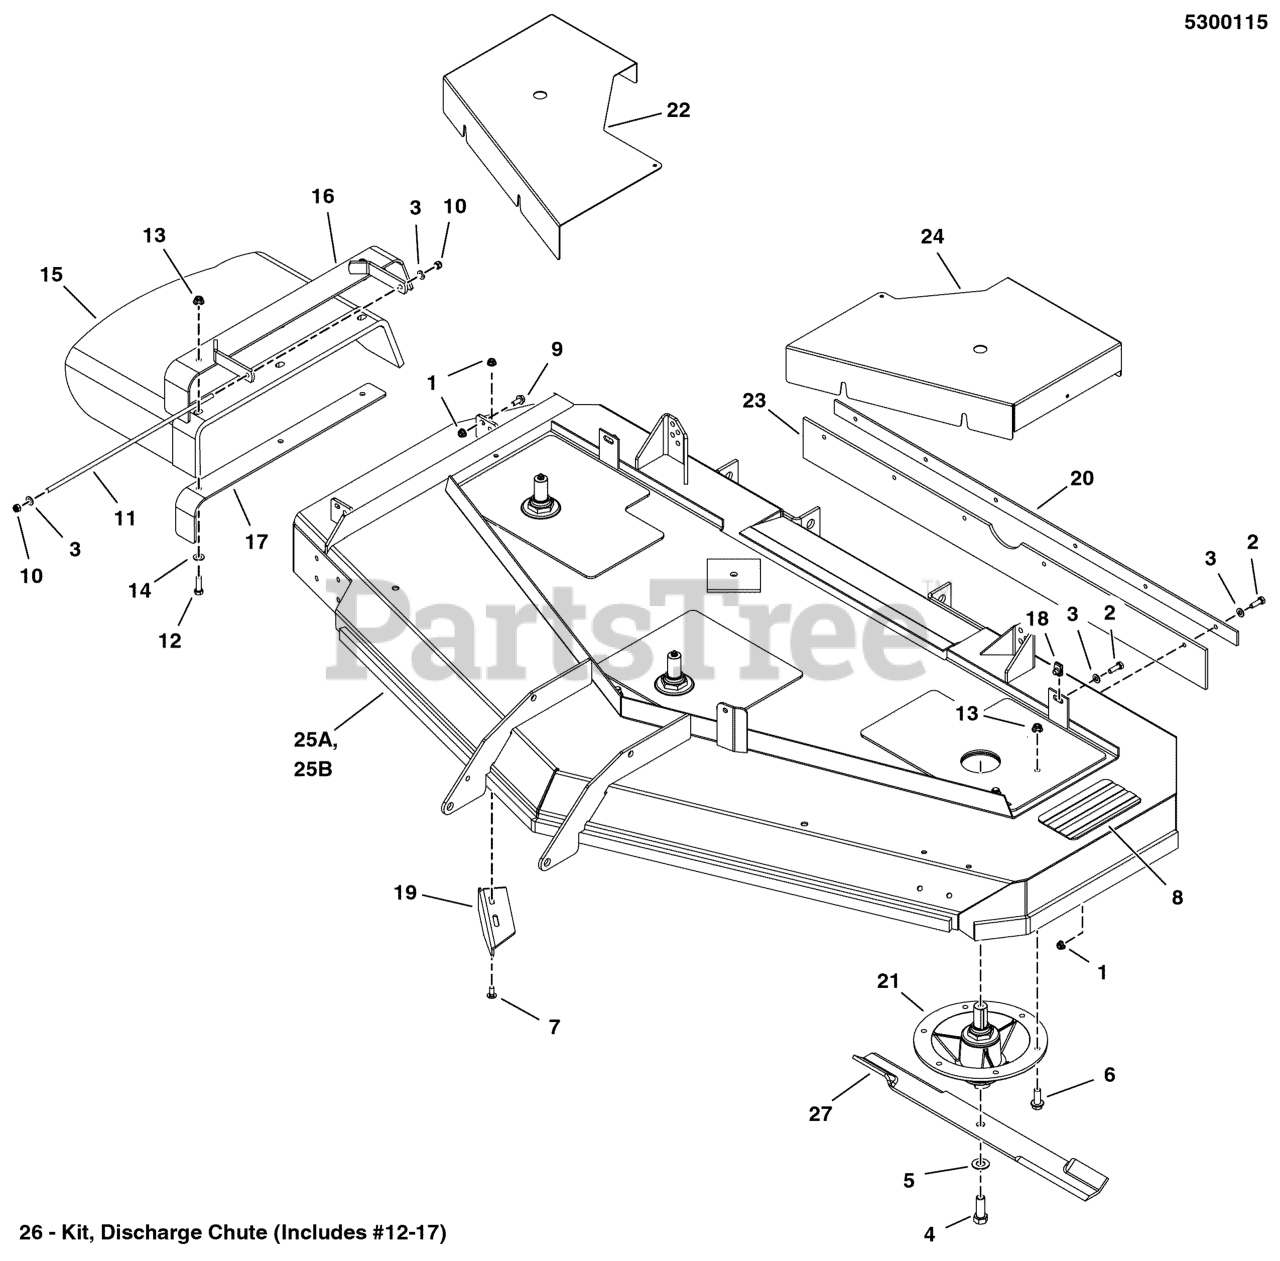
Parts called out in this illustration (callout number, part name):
1	NUT, 5/16-18 HEX NYLOCK FLANGE
2	BOLT, 5/16-18 X 1 GD5 YZ
3	WASHER, 5/16" SAE
4	BOLT, 5/8-11 X 1-3/4 GD8
5	WASHER, 5/8 GRADE 8, YZ
6	BOLT, 3/8-16 X 1-1/4, FLANGE, GD 5, CZ
7	BOLT, 5/16-18 X 3/4, CARRIAGE
8	SAFETY WALK, 4.00 X 7.50
9	BOLT, 5/16-18 X 3/4 GD5
10	NUT, 5/16-24 HEX NYLON LOCK
11	ROD, MOUNT, CHUTE, 72, CZ
12	BOLT, 3/8-16 X 1-1/2" GD5 CZ
13	NUT, 3/8-16 HEX NYLOCK FLANGE
14	WASHER, 3/8 SAE
15	CHUTE, DISCHARGE, RUBBER, 61/72, BENT
16	WELD, FRAME, CHUTE, 72 - BLK
17	SUPPORT, DICHARGE CHUTE - BLK
18	BODY CLIP, 5/16-18-7GA MATERIAL
19	PLATE, DEFLECTOR, 72 - BLK
20	PLATE, SUPPORT, 72" - BLK
21	SPINDLE ASSEMBLY
22	GUARD, 72", RH
23	FLAP, STRIPER, 72
24	GUARD, 72", LH
25A	DECK SHELL W/ DECALS, 72
25B	DECK SHELL W/ DECALS, 72, ANSI-EXP
26	KIT, DISCHARGE CHUTE, 72, ZTR
27	BLADE, 25 X 25 X 2.50, HIGH LIFT (SET OF 3)
